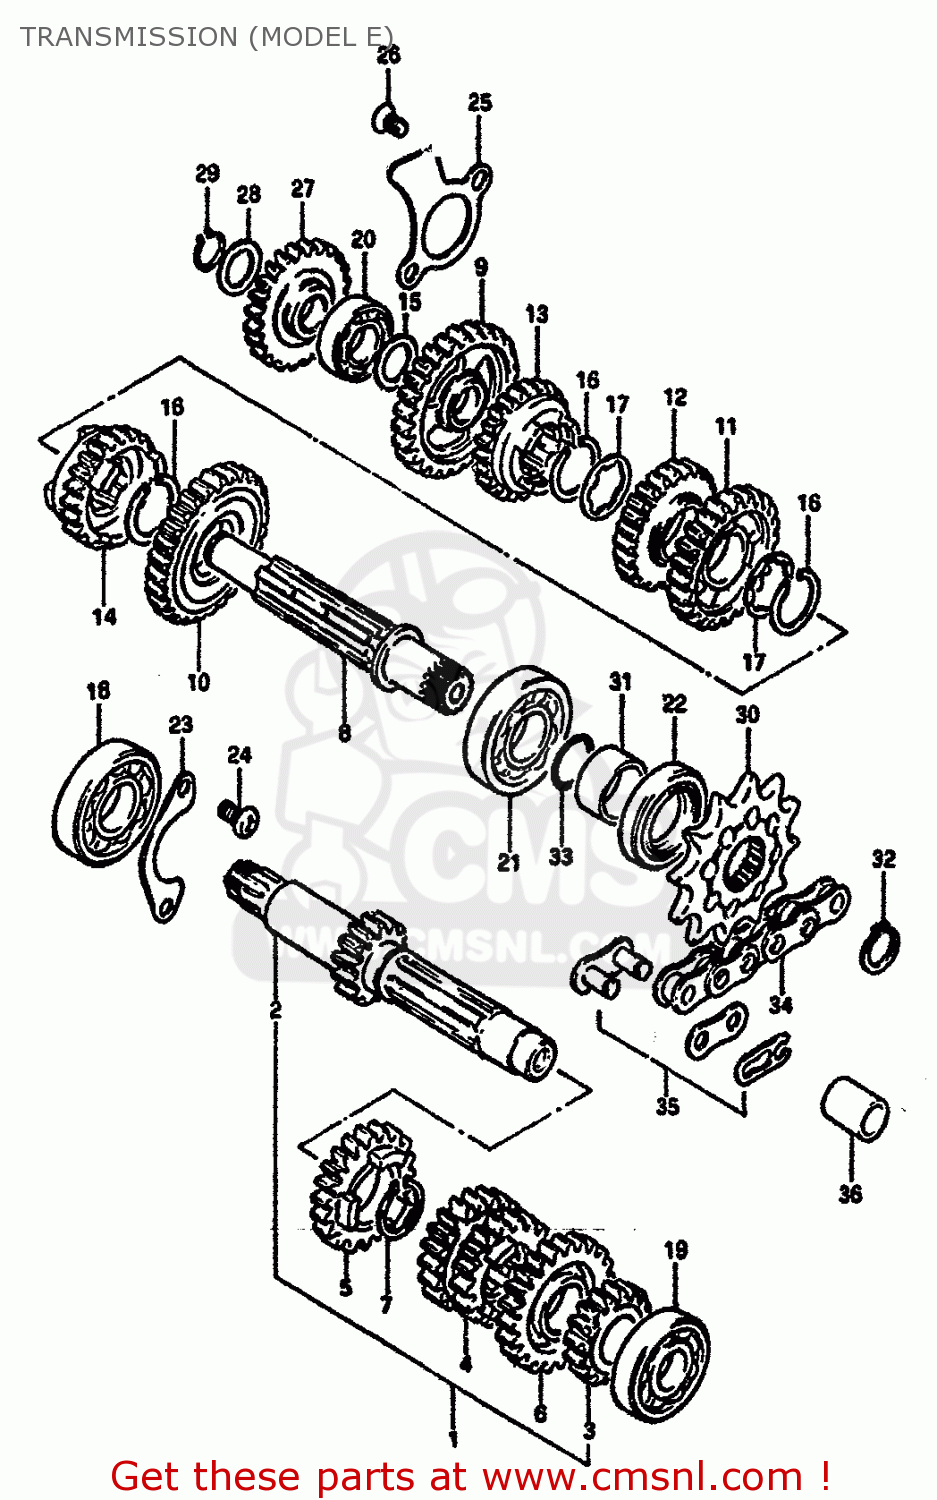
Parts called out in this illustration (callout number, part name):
1	COUNTER SHAFT ASSEMBLY
2	SHAFT,COUNTER
3	GEAR,2ND DRIVE
4	GEAR,THIRD & FOURTH DRIVE
5	GEAR,FIFTH DRIVE
6	GEAR,6TH DRIVE(NT:23)
7	CIRCLIP
8	SHAFT,DRIVE
9	GEAR,FIRST DRIVEN (NT:31)
10	GEAR,SECOND DRIVEN
11	GEAR,THIRD DRIVEN (NT:24)
12	GEAR,FOURTH DRIVEN (NT:25)
13	GEAR,FIFTH DRIVEN (NT:23)
14	GEAR,SIXTH DRIVEN (NT:22)
15	WASHER,THRUST
16	CIRCLIP
17	WASHER,LOCK
18	BEARING
19	BEARING
20	BEARING
21	BEARING(20X47X14)
22	SEAL,OIL(25X40X7)
23	RETAINER,CNTR SHAFT BEARING
24	SCREW 6X12
25	RETAINER,DRIVESHAFT
26	SCREW
27	GEAR,KICK STARTER IDLE
28	WASHER,THRUST
29	CIRCLIP,15MM
30	SPROCKET,ENGINE
31	SPACER(20X25X12.5)
32	CIRCLIP
33	O RING(D:1,ID:19.5)
34	CHAIN ASSEMBLY,DRIVE
35	JOINT ASSEMBLY,CHAIN
36	CUSHION 12X20X20
